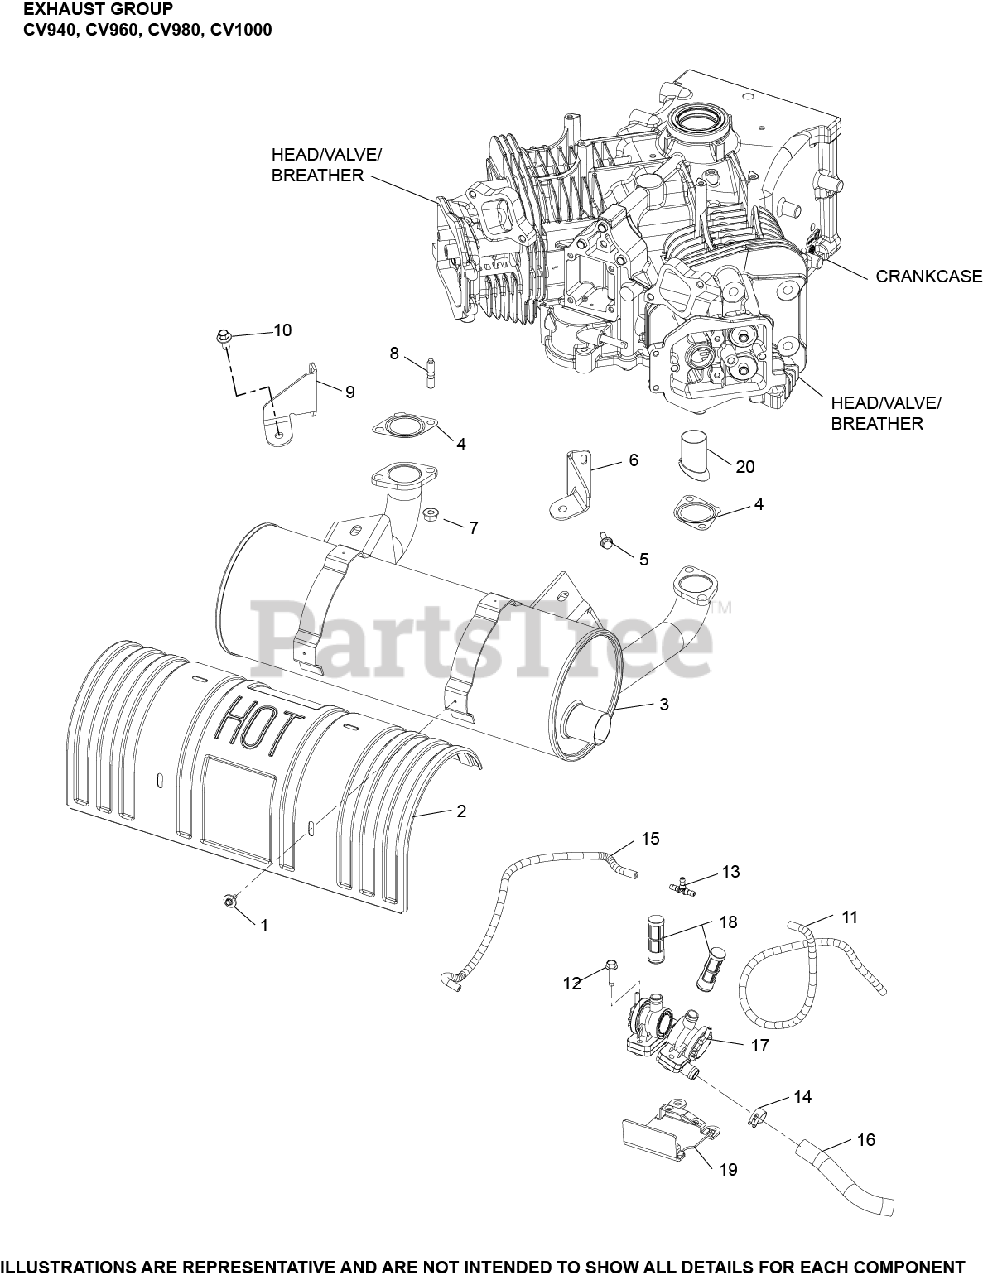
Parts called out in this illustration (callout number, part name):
1	SCREW, SEMS DRILL #8-18X1/2"
2	SHIELD, HEAT
3	KIT, MUFFLER VERTICAL
4	GASKET, EXHAUST
5	SCREW,FLG THD FRM M6X1.0X20-(#25086396S)
6	BRACKET, MUFFLER CYL #2
7	NUT, FLG M8X1.25
8	STUD, EXHAUST (KM)-USE 25 072 24-S
9	BRACKET, MUFFLER CYL #1
10	SCREW, FLG 8X1.25X16
20	LINER, EXHAUST PORT
